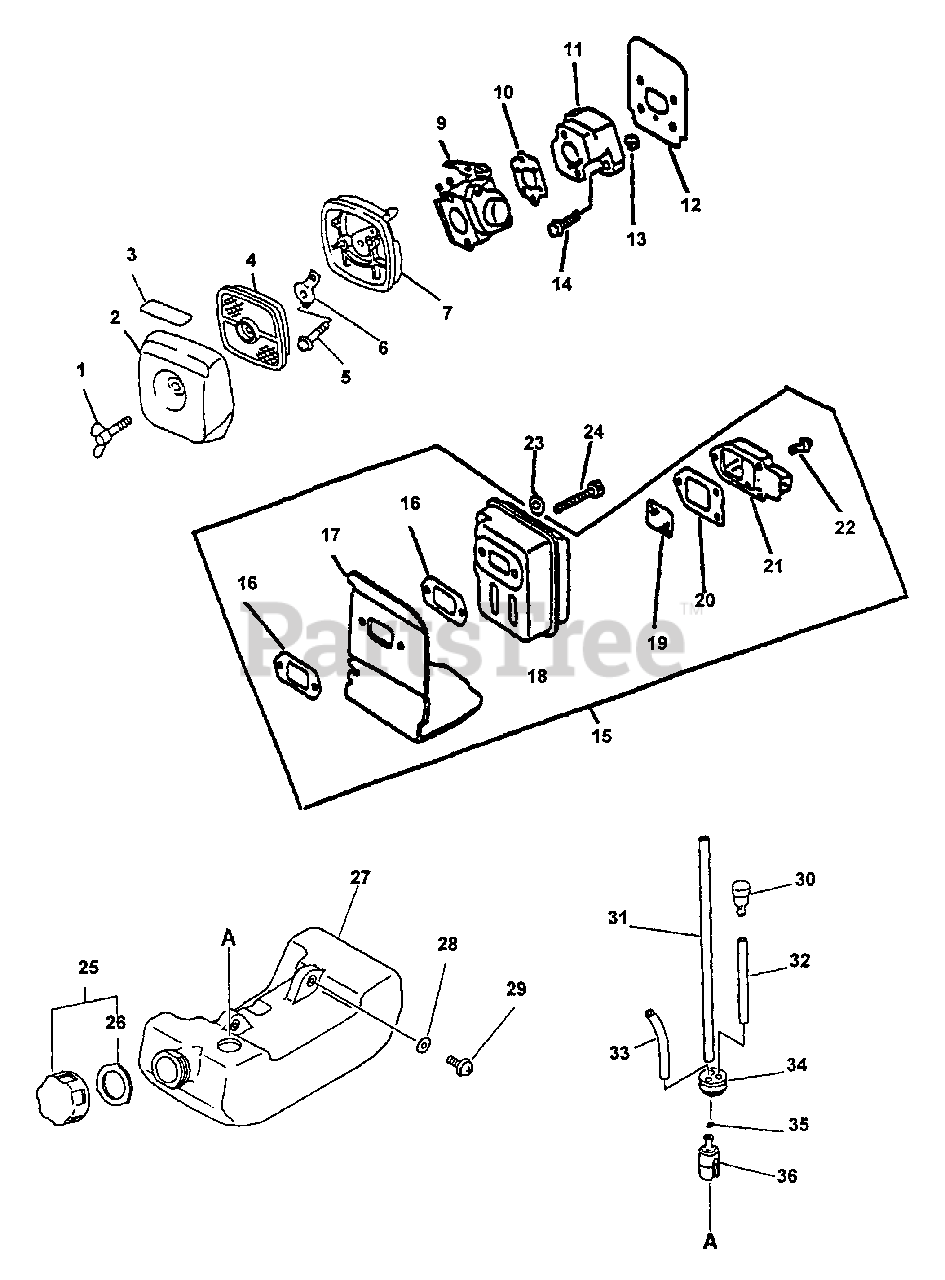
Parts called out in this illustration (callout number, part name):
1	THUMBSCREW
2	COVER, AIR FILTER - GRAY
3	LABEL - CHOKE
4	FILTER, AIR - SINGLE LAYER
5	SCREW - 5X65
6	PLATE, PREVENT
7	AIR FILTER CASE ASSY
9	CARBURETOR C1U-K47
10	GASKET, INTAKE
11	INSULATOR, INTAKE
12	SHIELD, INTAKE
14	SCREW - 5X20
15	MUFFLER ASSY
16	GASKET, EXHAUST
17	COVER, EXHAUST
18	MUFFLER ASSY
19	SCREEN, SPARK ARRESTOR
20	GASKET, EXHAUST
21	GUIDE, EXHAUST - OUTER
22	SCREW - 4X10
23	WASHER - 5
24	SCREW - 5X55
25	CAP ASSY
26	GASKET, CAP
27	FUEL TANK ASSY
28	WASHER - 5
29	SCREW - 5X16
30	VENT, FUEL TANK
31	PIPE - 3X5X180 -- BLACK
32	PIPE - 3X5X70 -- BLACK
33	PIPE - 3X6X90 -- CLEAR
34	GROMMET
35	CLIP - 6
36	FILTER, FUEL
